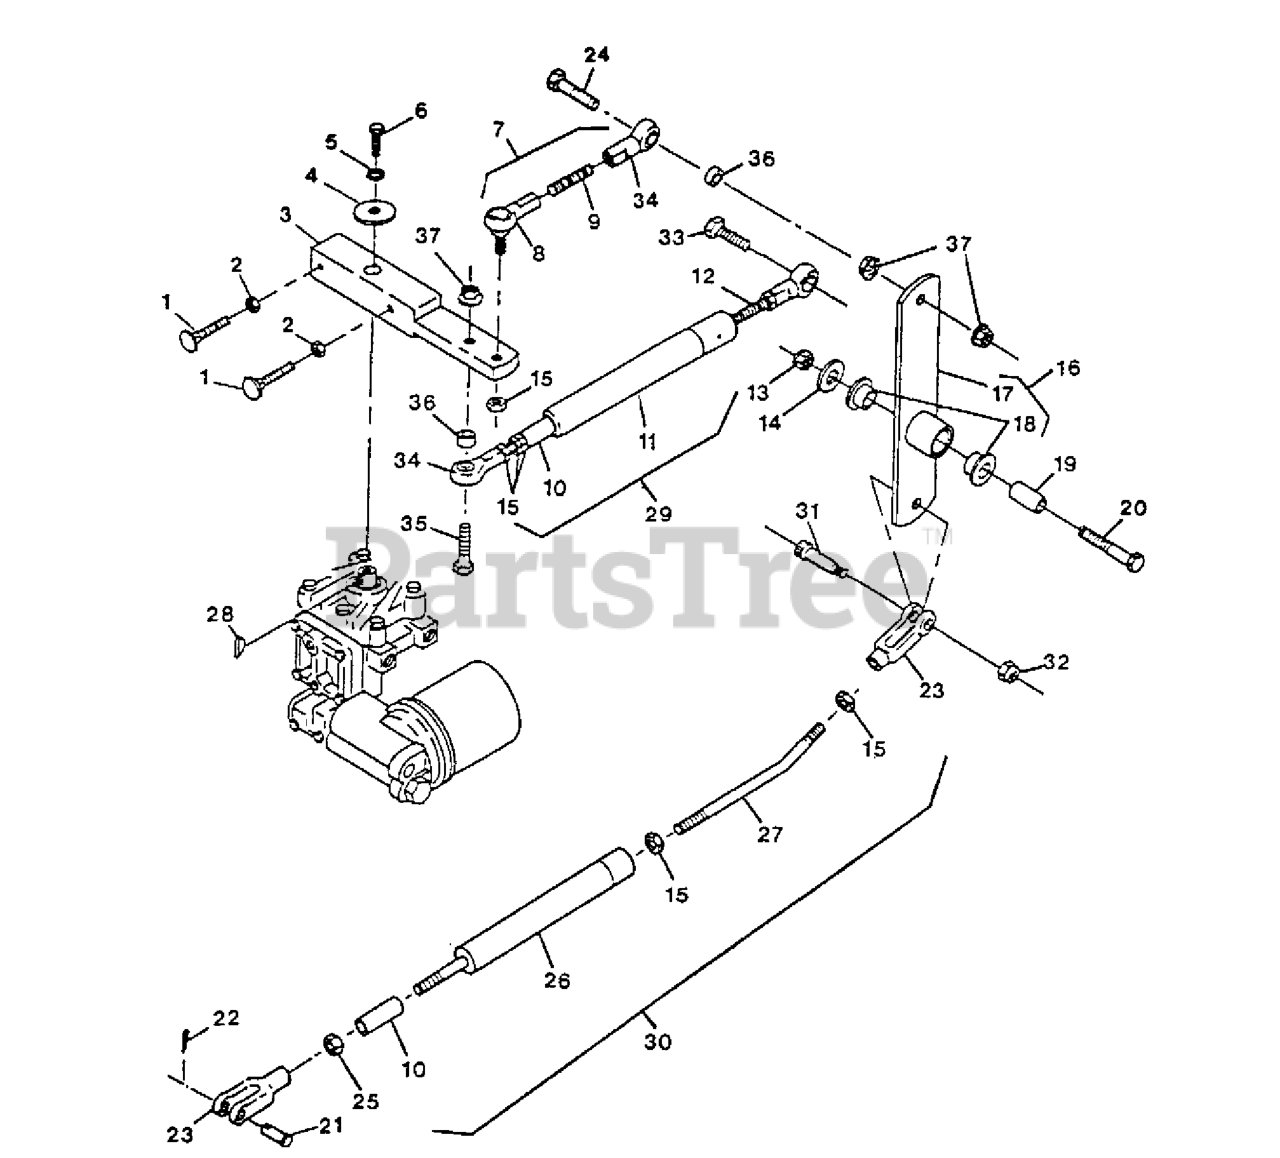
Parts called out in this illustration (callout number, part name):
2	NUT-HEX
3	WLD,ARM TRANSAXLT
4	WASHER-RETAINER, PULLEY
5	WASHER-LOCK
6	Capscrew, 1/4-20 X 1-1/2
8	BALLJOINT
9	ROD END PLTD.
10	BUSHING,SPRING GUIDE
12	ROD,END
13	NUT-LOCK, NI
14	WASHER-FLAT
15	NUT-JAM
17	WLD,IDLER LINKAGE
18	BEARING-CONTROL
19	BUSHING,MOTION LEVER
20	SCREW-HH
21	PIN-CLEVIS
22	PIN-COTTER
23	YOKE-ADJUSTABLE
24	SCREW-HH
25	NUT-HEX
27	LINKAGE,ROD
28	KEY-WOODRUFF
30	ASM,PEDAL OVERRIDE
31	SCREW-HSH
32	NUT-LOCK, NI
33	SCREW-HH
34	BALLJOINT-RH
35	SCREW-HH
36	SPACER-PLATED
